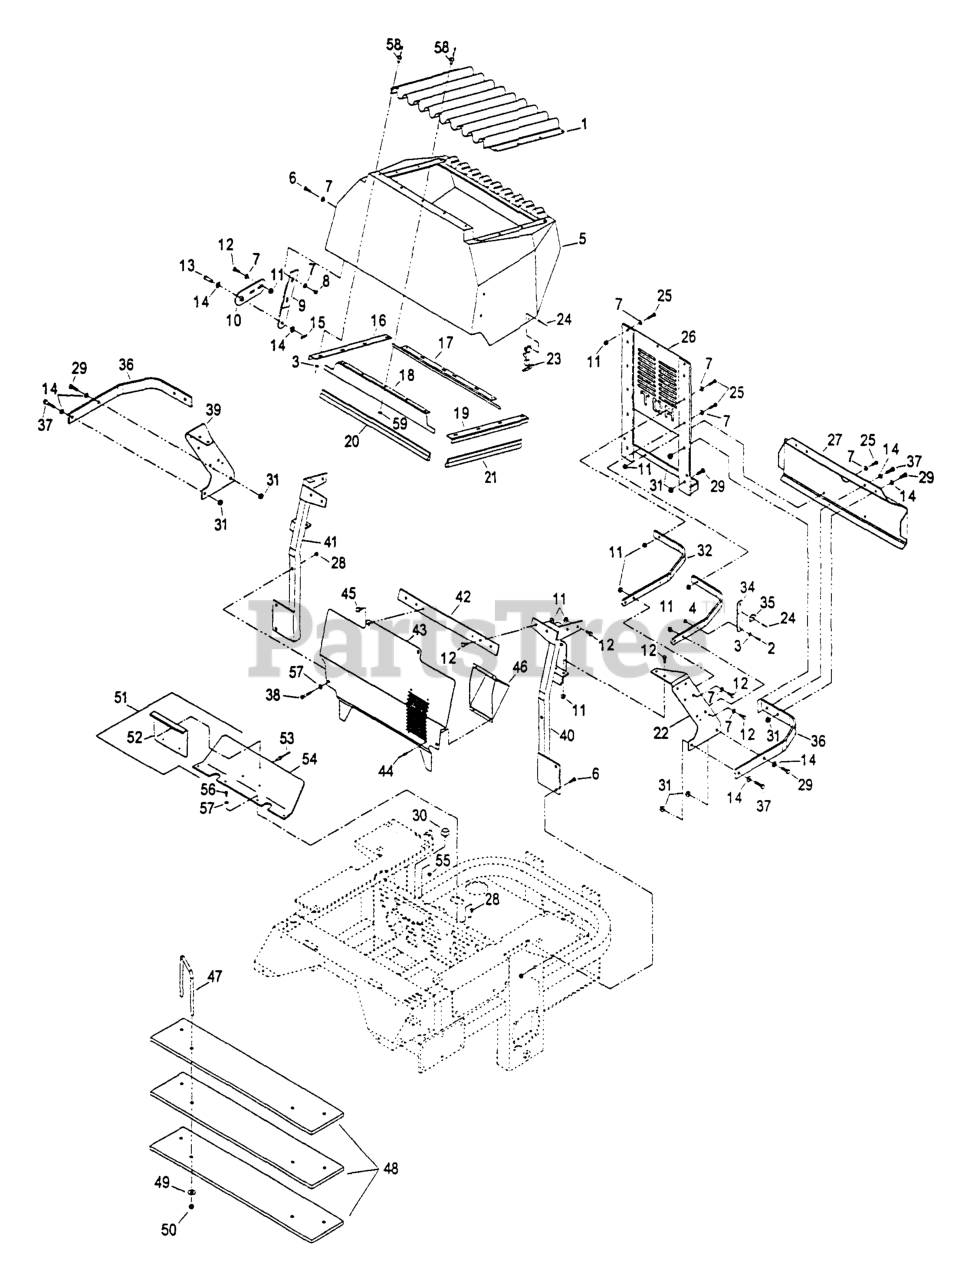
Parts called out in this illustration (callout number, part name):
1	SCREEN-RADIATOR
9	PLATE-HINGE, HOOD
10	SHACKLE-HINGE
13	PIN-CLEVIS
15	PIN-COTTER
16	ANGLE-RADIATOR, RH
17	ANGLE-RADIATOR, BOTTOM
18	ANGLE-RADIATOR, TOP
19	ANGLE-RADIATOR, LH
20	SEAL-TRIM
21	SEAL-TRIM
23	LATCH-RUBBER
34	Bar, Latch Hook
40	BRACE-RADIATOR, LH
43	Deflector, Air
44	Pop Rivet- Stl 3/16x.250
46	PLENUM-INTAKE, AIR
52	Shield, Lift
53	RIVET-POP
59	WASHER-SPRING
